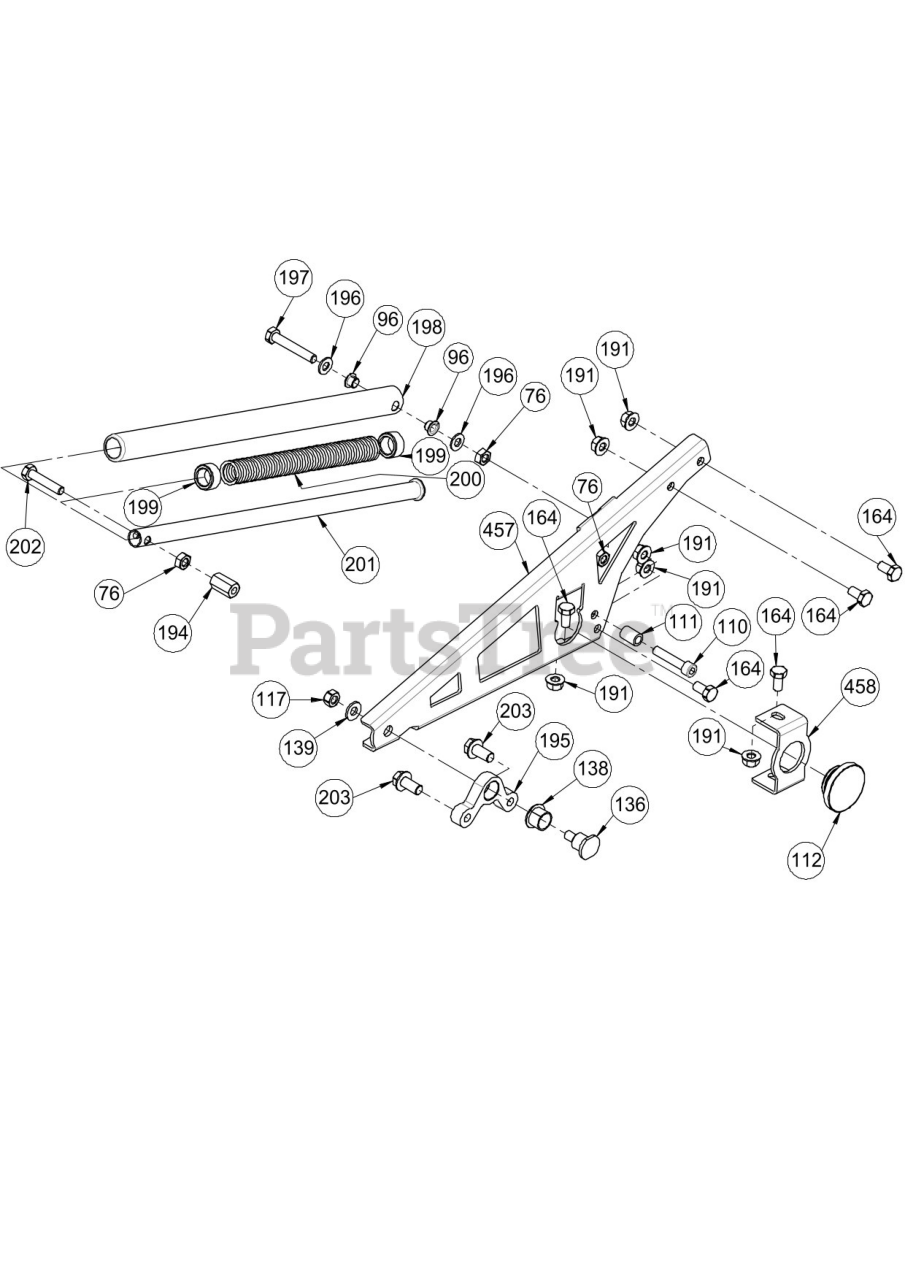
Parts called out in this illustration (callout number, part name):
76	NUT, HEX M10 DIN 934 8 ZCC
96	BHSG, DU FLG BB1009DU
110	SCR, SKH M10X50 DIN ISO 4762 10.9
117	NUT, LK V-M10 DIN 980
136	SCREW, COLLAR
138	BHSG, DU FLG BB201DU
139	WHSR, BLVL M10 DIN 6796
164	BLT, HEX M10X20 DIN 933 8.8 ZCC
191	NUT, FLG SLF LK M10 CL 8 ZCC
194	NUT, COUPLING M10 DIN 6334 ZCC
195	BRKT, PIVOT
196	WSHR, FLT A M10.5 DIN 125 ZCC
197	BLT, HEX M10X65 DIN 931 10.9 (BLK)
198	SLEEVE, SPRING
199	GUIDE, SPRING
200	SPRING, COMPRESSION
201	TUBE, SPRING
202	BLT, HEX M10X50 DIN 931 8.8 ZCC
203	BLT, SER FLG M12X25 VERBUS RIPP 100
457	BRACKET, HOOD ARM
458	ANGLE, SETTING
